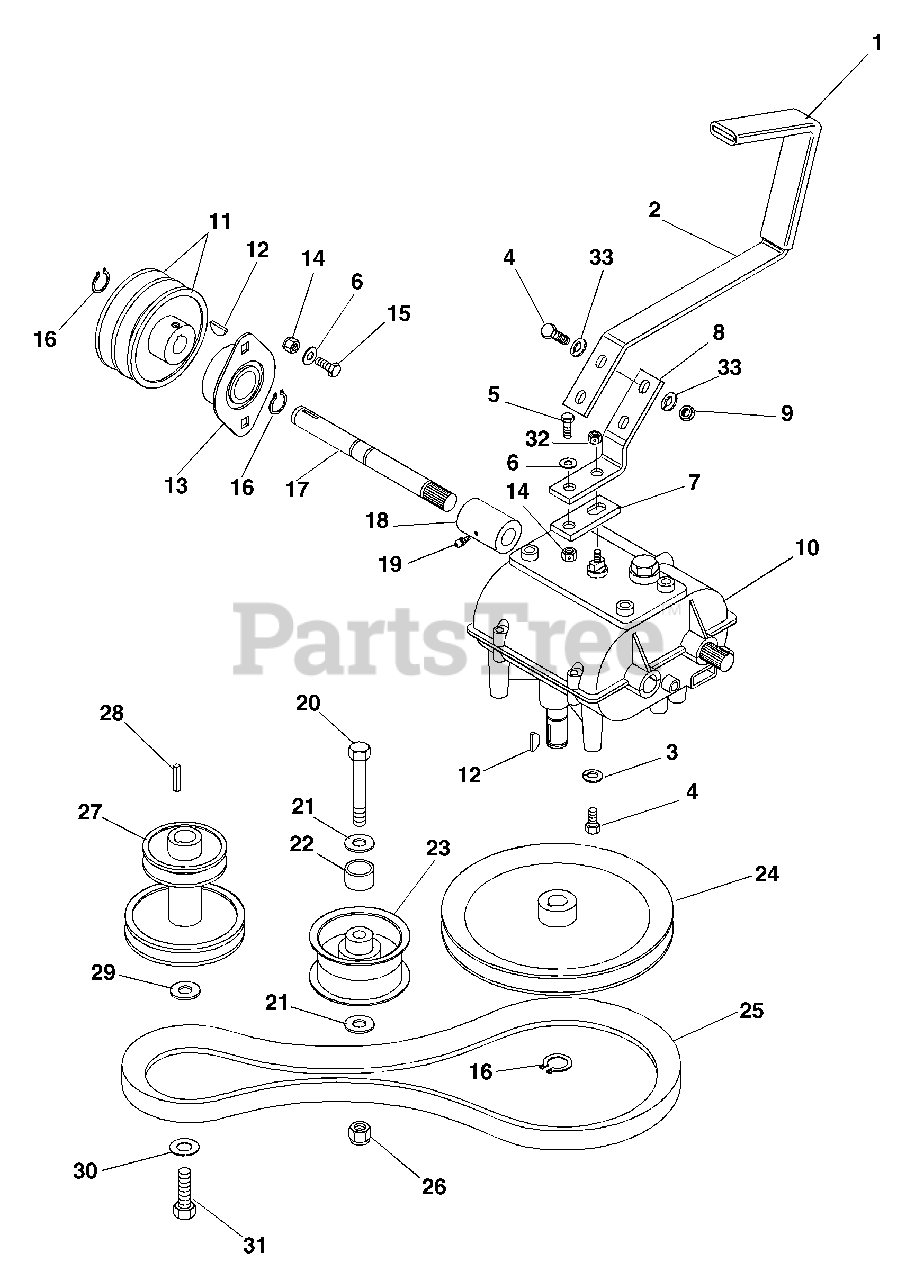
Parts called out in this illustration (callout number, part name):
1	Grip
2	Lever, Transmission Shift
3	Washer-Locking .31 x .078 Regular
4	Bolt-Hex .31-18 x 1.00 Grade 5
5	Bolt-Hex .25-20 x 1.00 Grade 5
6	Washer-Flat-STL .281 x .62 x .065
7	Plate, Shift
8	Arm, Shift
9	Nut-Locking-Center .31-18
10	Transmission
11	Drive Sheave (Upper)-Pro-150
12	Key-Woodruff .19 x .75
13	Bearing-Flange .625X1.875X.797
14	Nut-Locking-Center .25-20
15	Bolt-Hex .25-20 x .75 Grade 5
16	Ring-Retaining-External .579 x .930
17	Shaft, Half
19	Fitting,Lube, .25-28
20	Bolt-Hex .38-16 x 2.25 Grade 5
21	Washer-Flat-Steel .406 x .812 x .065
22	Spacer .625 x 3.85 x .55
23	Idler- Pulley Flat 3.25 x .625
24	Pulley-V 7.50 x .63 Sheave Transmission
25	V-Belt A-Section 14.9 x .516
26	Nut-Locking-Center .38-16
27	Crank Sheave-Pro
28	Key-Square .248 x 2.38
29	Washer Lock .44 Regular
30	Washer-Special .47 x 2.00 x .25
31	Bolt-Hex M10 x 1.5 x 60 8.8
32	Nut-Locking-Center .38-24
33	Washer-Flat-Steel .344 x .688 x .065
